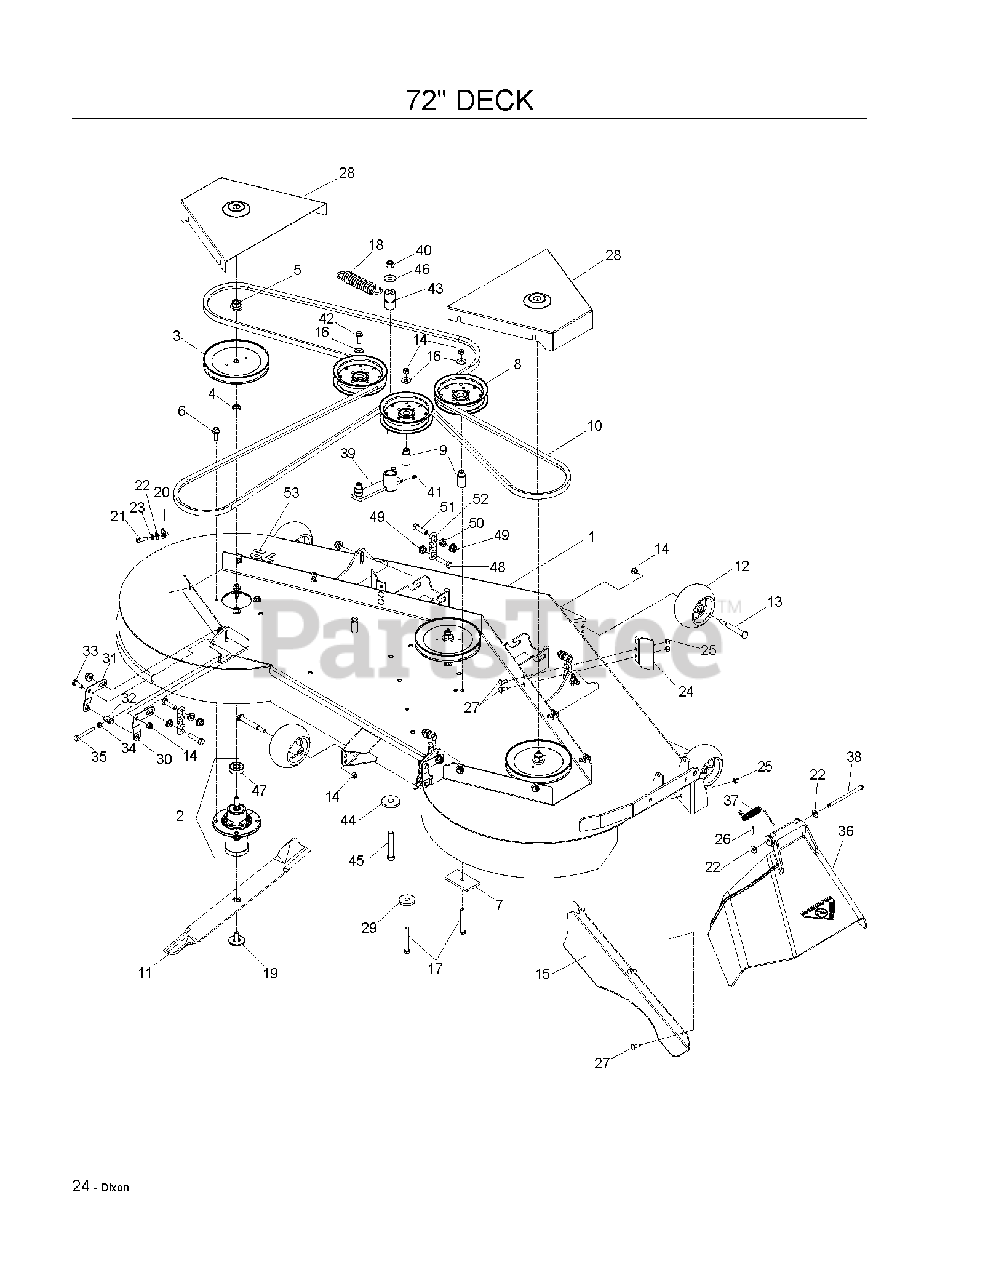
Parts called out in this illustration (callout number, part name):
1	DECK W/DECALS, 72" DIX
2	MANDREL.DECK.ASSEMBLY
4	WASHER-SPACER
5	LOCKNUT - 9/16
6	WASHER HEAD SCREW
7	SUPPORT PLATE
8	PULLEY, IDLER
9	IDLER BUSHING
10	BELT, DECK
11	BLADE, 25"
12	GAUGE WHEEL
13	SHOULDER BOLT 1/2X2-5/8 ZD SPE
14	NUT 3/8-16 NYLOC
15	CONFINEMENT PLATE, 72"
16	WASHER 3/8 FLAT
17	HCS 3/8C X 3
19	BLADE BOLT ASSY-7/16" TB REPL
20	U-CLIP 5/16-18 NUT RETAINER
21	HCS 5/16C X 1
22	WASHER 5/16 FLAT
23	WASHER 5/16 LOCK
24	DECK STOP
25	NUT 5/16 NYLOC
26	COTTER PIN 1/8 X 3/4
27	BOLT 5/16C X 3/4" CARRIAGE
28	SHIELD, BELT - 72" BLUE
29	SPINDLE WASHER
30	PITCH, ADJUST, RT
31	PITCH, ADJUST, LT
32	TRUNION, PITCH
33	HCS 3/8C X 1
34	NUT 5/16C HEX
35	HCS 5/16-18 X 2 1/2 TPBLT
36	DISCHARGE CHUTE - 72"
37	SPRING - TORSION
38	PIN-CLEVIS 5/16 DIA X 5.19 ZD
39	IDLER ARM
40	NUT 1/2-13 HEX NYLOC ZD
41	ZERK
42	HCS 3/8C X 1 SERRATED HEAD
43	PIVOT BUSHING
44	WASHER, SUPPORT
45	HCS 1/2C X 3 1/4
46	WASHER 1/2 FLAT
47	BEARING, BALL
48	HCS 7/16 - 14 X 1 3/4
49	NUT 7/16-14 HEX WHIZ LK
50	NUT 7/16C WHIZ
51	HCS 7/16C X 1 1/2
52	LIFT CHAIN - 3 LINK
53	DECAL, 72"
